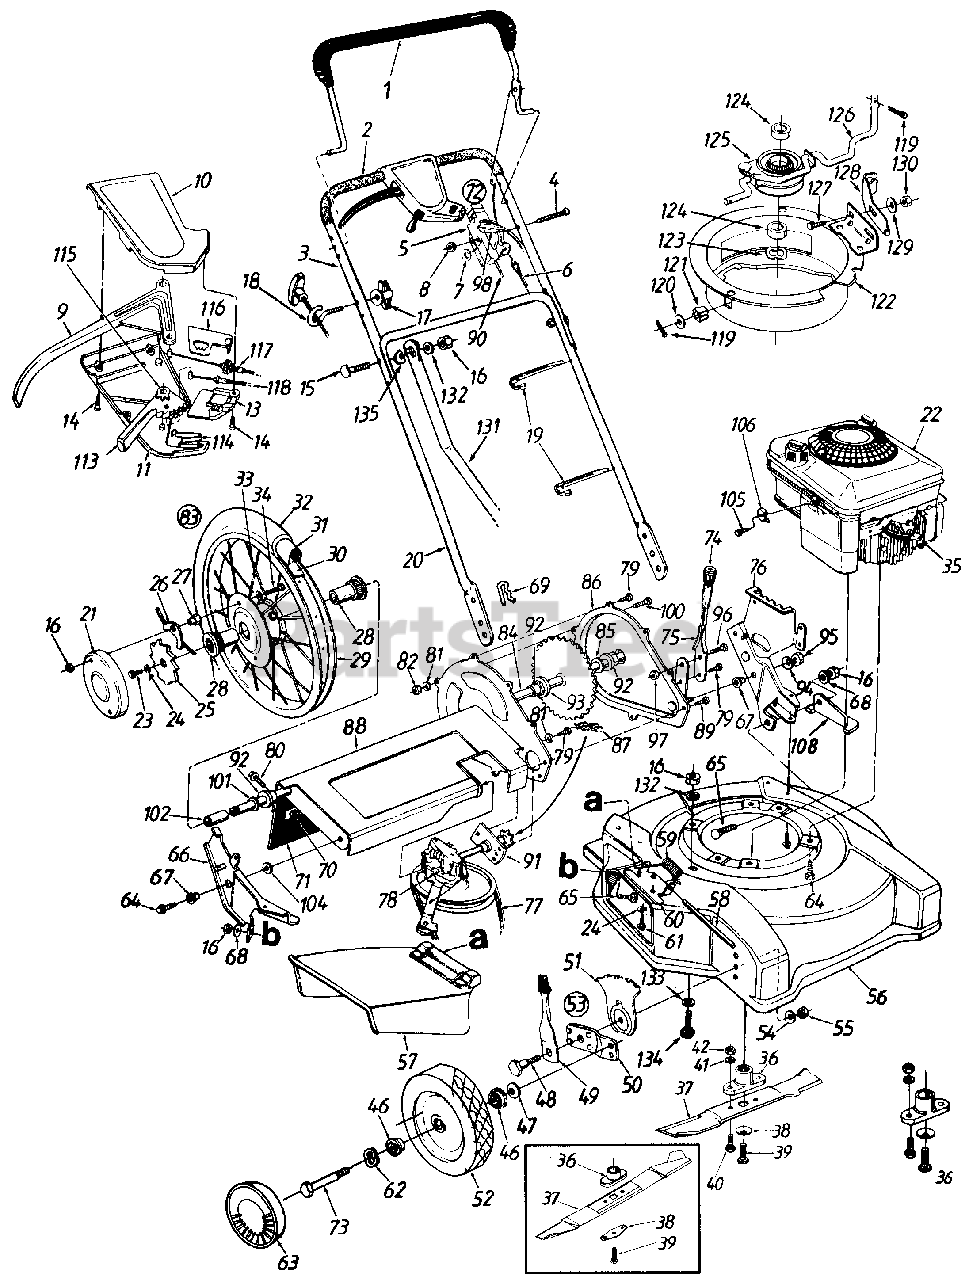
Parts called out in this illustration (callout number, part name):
1	Control Handle Ass'y.
2	Foam Grip
4	Oval C-Sunk Scr.
5	Throttle Body
6	Control Cable - 39" Lg.
7	Spring Wash. .66" I.D.
8	Hex L-Nut 1/4-20 Thd.
9	Control Lever
10	Control Cover Half - Upper
11	Control Cover Half - Lower
13	Cable Mounting Cap
14	Fl-"C" Sunk Scr. #10 x .75"
15	Curved Hd. Bolt 5/16-18 x 1.38"
16	Hex Nut 5/16-18 Thd.
17	Handle Knob 1/4-20 Thd.
19	Cable Tie
22	Engine
23	Hex Bolt 1/4-20 x .75" Lg. (Gr. 5)
24	Bell-Wash. 1/4" I.D.
25	Wheel Ratchet
26	Pawl and Spring Ass'y.
27	Special Hex Nut 5/16-18 Thd.
28	Flange Bearing .63" I.D.
29	Rim Ass'y. Only 16" x 2.1"
30	Rimstrip 16" x 7/8"
31	Inner Tube 16" x 2.12"
32	Chevron Tire 16" x 2.125"
33	Intern. L-Wash. 5/16" I.D.
34	Hex Bolt 5/16-18 x 1.0" (Gr. 5)
35	Spark Plug Boot
36	Blade Adapter Kit
37	22" Blade
38	Bell Wash. .39" I.D.
39	Hex Bolt 3/8-24 x 1.5" Lg.
40	Hex Bolt 3/8-24 x 1" Lg.
41	L-Wash. 3/8" I.D.
42	Hex Nut 3/8-24 Thd.
46	Ball Bearing 1/2" I.D.
47	Bell-Wash. .38" I.D.
48	Shld. Bolt .5"
49	Spring Lever Ass'y. w/Knob
51	Height Adj. Plate
52	Wheel Ass'y. Comp.
53	Height Adj. Ass'y. Comp. - R.H.
54	Bell-Wash. .39" I.D. x 1.38"
55	Hex Nut 3/8-16 Thd.
58	Hinge Pin
60	Adapter Plate
61	Hex TT-Tap Scr. 1/4-20 x .5"
62	Wave Wash. .51" I.D. x .78"
63	Hub Cap
64	Hex TT-Tap Scr. 3/8-16 x 1"
65	Carriage Bolt 5/16-18 x .62" Lg.
68	Bell-Wash. 5/16" I.D.
69	Intern. Cotter Pin 5/16" Dia.
70	Retaining Strip
72	Throttle Box Comp.
73	Front Axle Bolt
75	Height Adjustment Lever
78	Trans. Comp.
79	Hex B-Tap Scr. 1/4 x .38" Lg.
80	Hex AB-Tap Scr. 1/4 x .62" Lg.
81	L-Wash. 1/4" I.D.
82	Hex Nut 1/4-20 Thd.
83	Wheel Ass'y. Comp.
84	Sprocket and Axle Ass'y.
85	Fl-Wash. .635" I.D. x 1.0" O.D.
90	Throttle Cable - 55" Lg.
92	Hex Flange Brg. .631" I.D.
93	Spacer .63" I.D. x 1.25"
95	Hex L-Nut 3/8-24 Thd.
96	Hex Bolt 3/8-16 x .62" Lg.
97	Flanged L-Nut 3/8-16 Thd.
98	Throttle Lever
100	Hex Bolt 1/4-20 x .5" Lg.
101	Fl-Wash. .632" I.D. x .943"
102	Spacer .628" I.D. x .875"
104	Fl-Wash. .38" I.D. x 1" O.D.
105	Wash. Hd. Scr. #10-32 x .62" Lg.
106	Casing Clamp
108	Deck Bracket
113	6-Spd. Shift Lever
114	Shift Lever Spring
115	3-Tooth Rack Gear Insert
116	6-Speed Rack Cable Brkt.
117	S.P. Cable
118	Spd. Control Cable - 50" Lg.
119	Cotter Pin 3/32" Dia.
120	Fl-Wash. .33" I.D. x .687" O.D.
121	Flanged Bushing
124	Spacer .885" I.D. x 1" O.D.
125	Pulley Ass'y.
127	Carr. Bolt 1/4-20 x .5" Lg.
130	Hex L-Nut 1/4-20 Thd.
133	Fl-Wash. 7/16" I.D. x 7/8" O.D.
134	Carriage Bolt 5/16-18 x .62" Lg.
135	Saddle Wash. .32" I.D. x .93"
